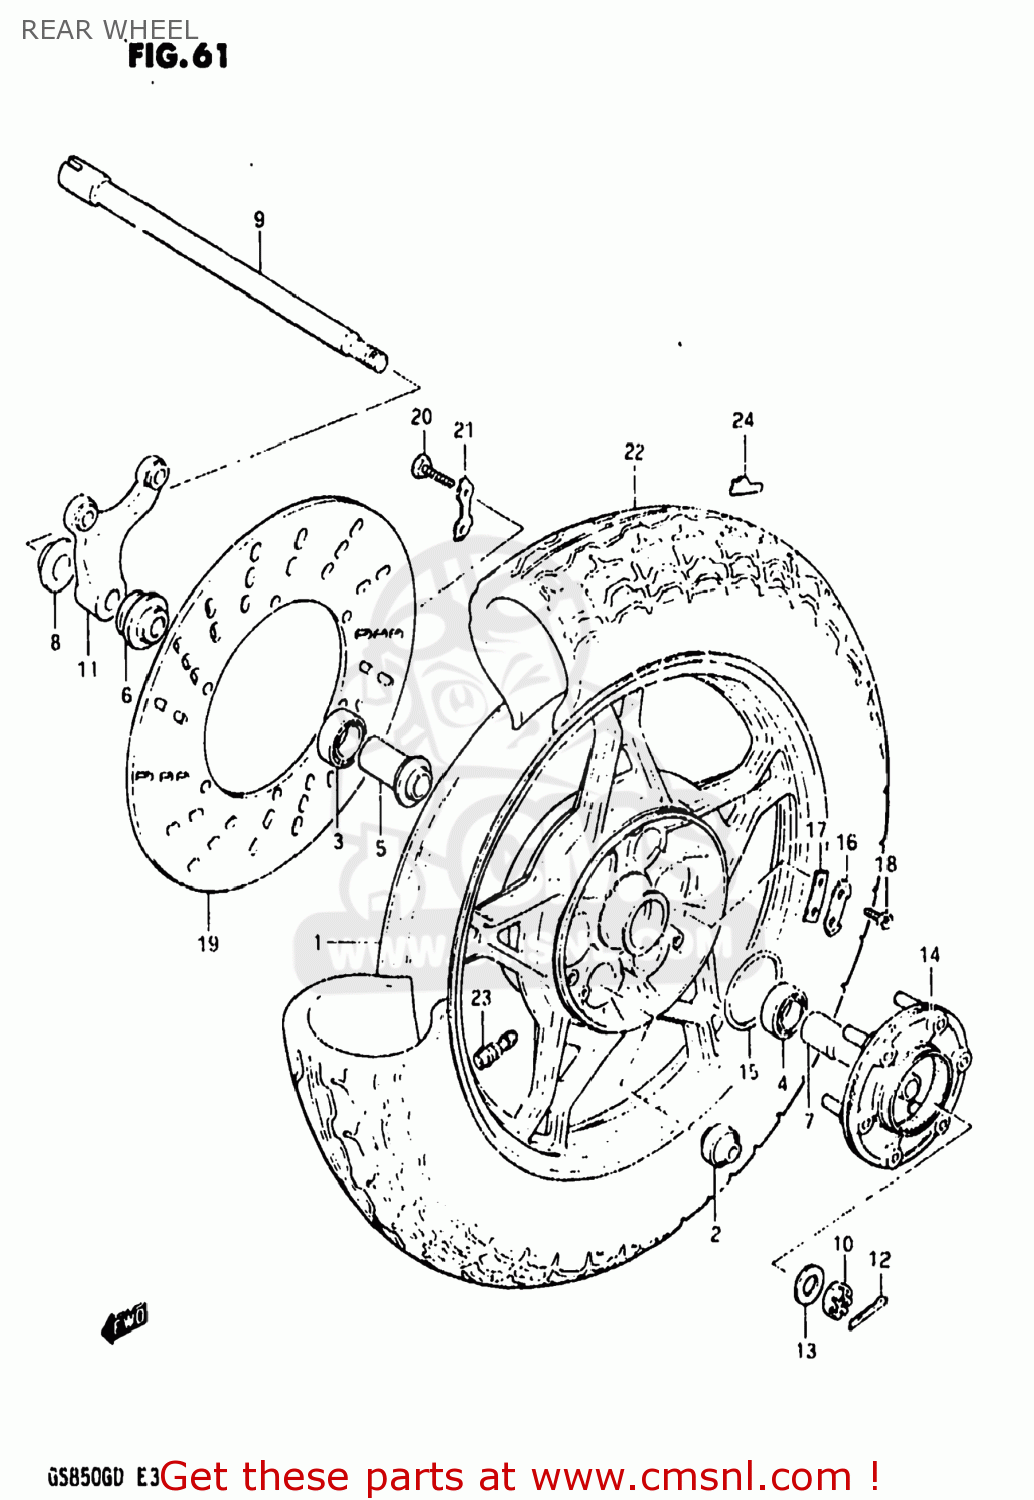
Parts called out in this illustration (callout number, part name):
1	CASTING WHEEL,REAR 2.50
2	BUSH
3	BEARING
4	BEARING
5	SPACER,REAR HUB BEARING
6	SPACER,REAR AXLE
7	SPACER,REAR AXLE,LEFT
8	SPACER,REAR AXLE,RIGHT
9	AXLE,REAR
10	NUT
11	BRACKET,RR,CALIPER
12	PIN,COTTER
13	WASHER (17.5X36X3.2)
14	JOINT ASSEMBLY,REAR HUB DRUM
15	O RING(D:2.1,ID:65)
16	WASHER
17	WASHER,THRUST(T:1.6)
18	BOLT(6X16)
19	DISC,RR BRAKE
20	BOLT(8X25)
21	WASHER
22	TIRE
23	VALVE ASSEMBLY,WHEEL RIM,J
24	BALANCER,WHEEL
